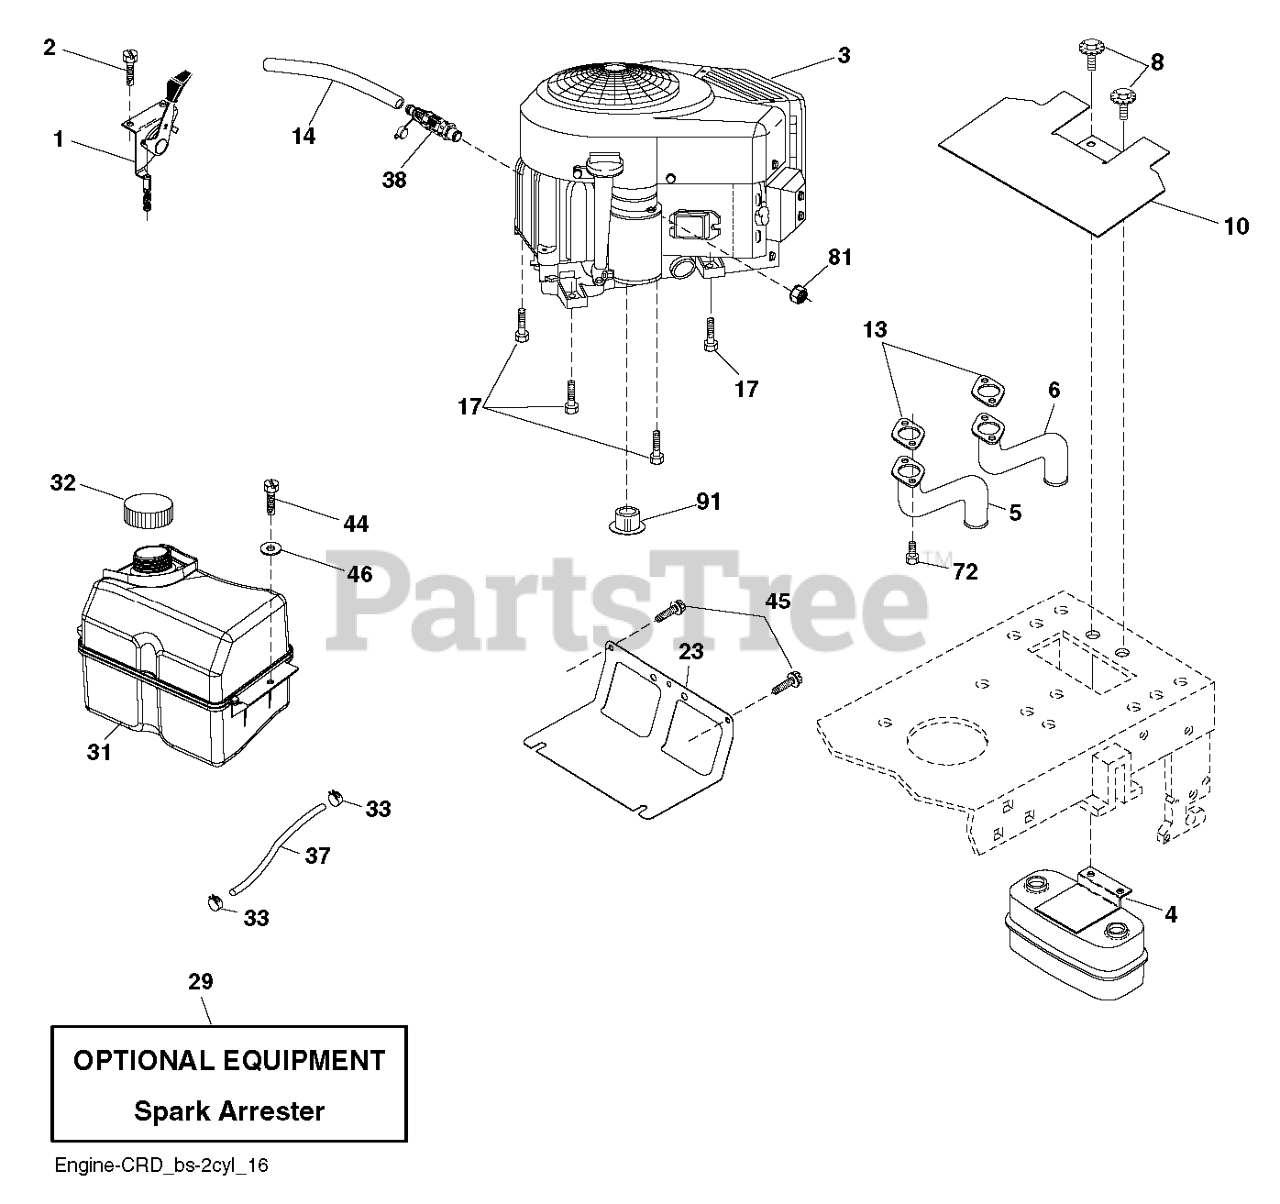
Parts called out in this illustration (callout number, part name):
1	CONTROL.TH/CK.COBRA.B&S.TWN.BK
2	SCREW.#10 X 0.750.BOS
4	MUFFLER.TWIN.CYL.LOW.TONE
5	RP.EXHAUST.TUBE.LH.BS/TWIN
6	EXHAUST.TUBE.RH.BS/TWIN
8	BOLT.5/16-18UNCX3/4 W/SEMS.BLK
10	SHIELD.HEAT.MUFFLER
13	GASKET.MUFFLER
14	TUBE, DRAIN OIL ASM.
17	SCREW.3/8-16
23	SHIELD.BROWNING.DBR.GUARD
29	KIT.SPARK ARRESTOR 794945 B&S
31	TANK.ASM.FUEL.FR.2.5GA.
32	CAP ASM.FUEL.2.25"FR.
33	HOSE CLAMP
37	LINE.FUEL.20
38	VALUE.OIL.DRAIN
44	SCREW HEXWSHR 1/4-20X3/4
45	SCREW, 3/8-16X3/4
72	SCREW.SOCKET.HEAD.5/16-18
81	NUT
91	BUSHING.1.375OD
